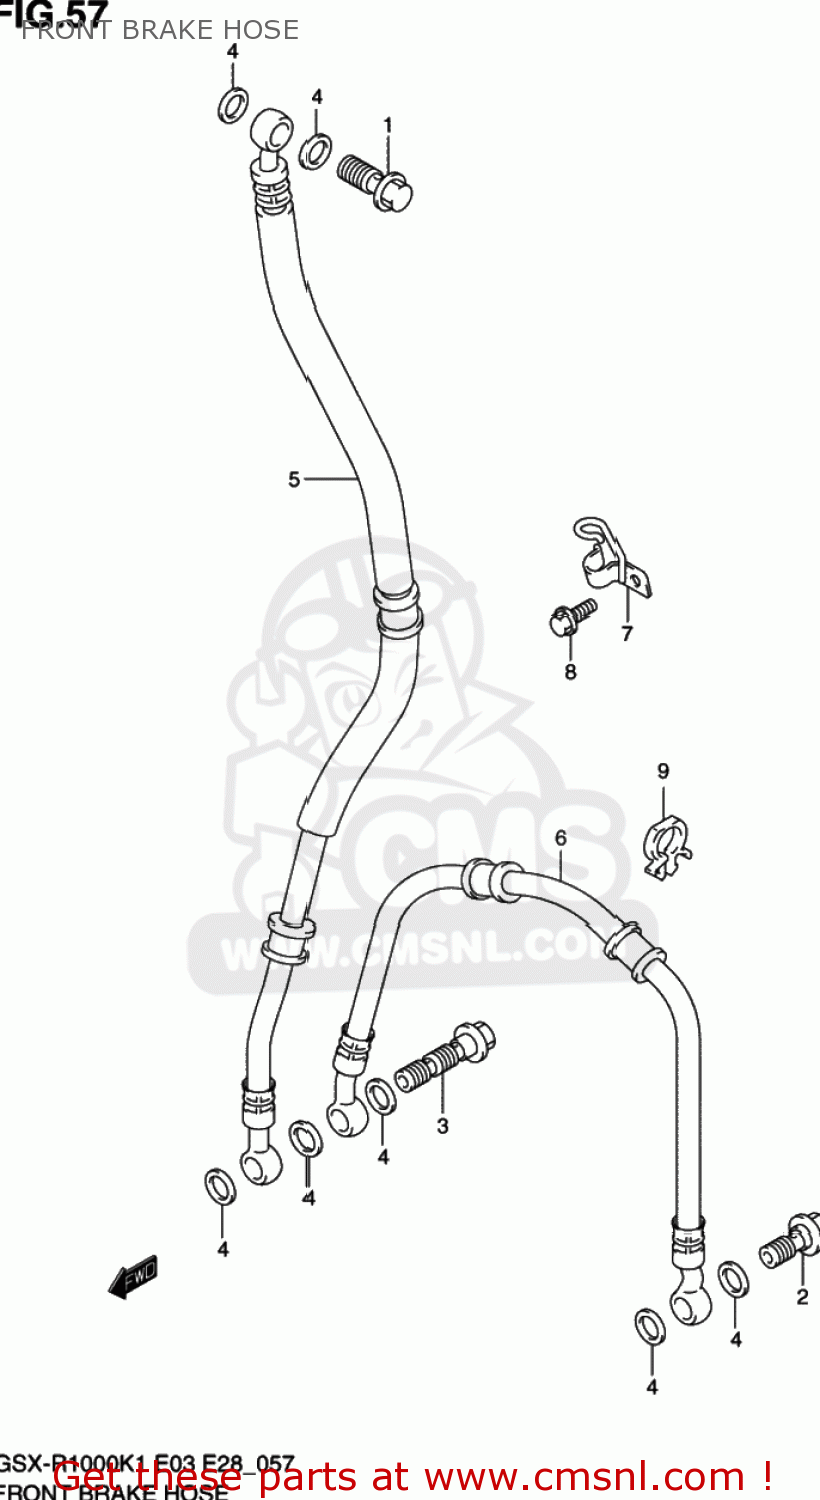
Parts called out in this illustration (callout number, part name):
1	BOLT UNION
2	BOLT UNION
3	BOLT UNION
4	WASHER(10X15X1.5)
5	HOSE,FR BRAKE NO.1
6	HOSE,FR BRAKE NO.2
7	CLAMP,FR BRAKE HOSE
8	BOLT
9	CLAMP
